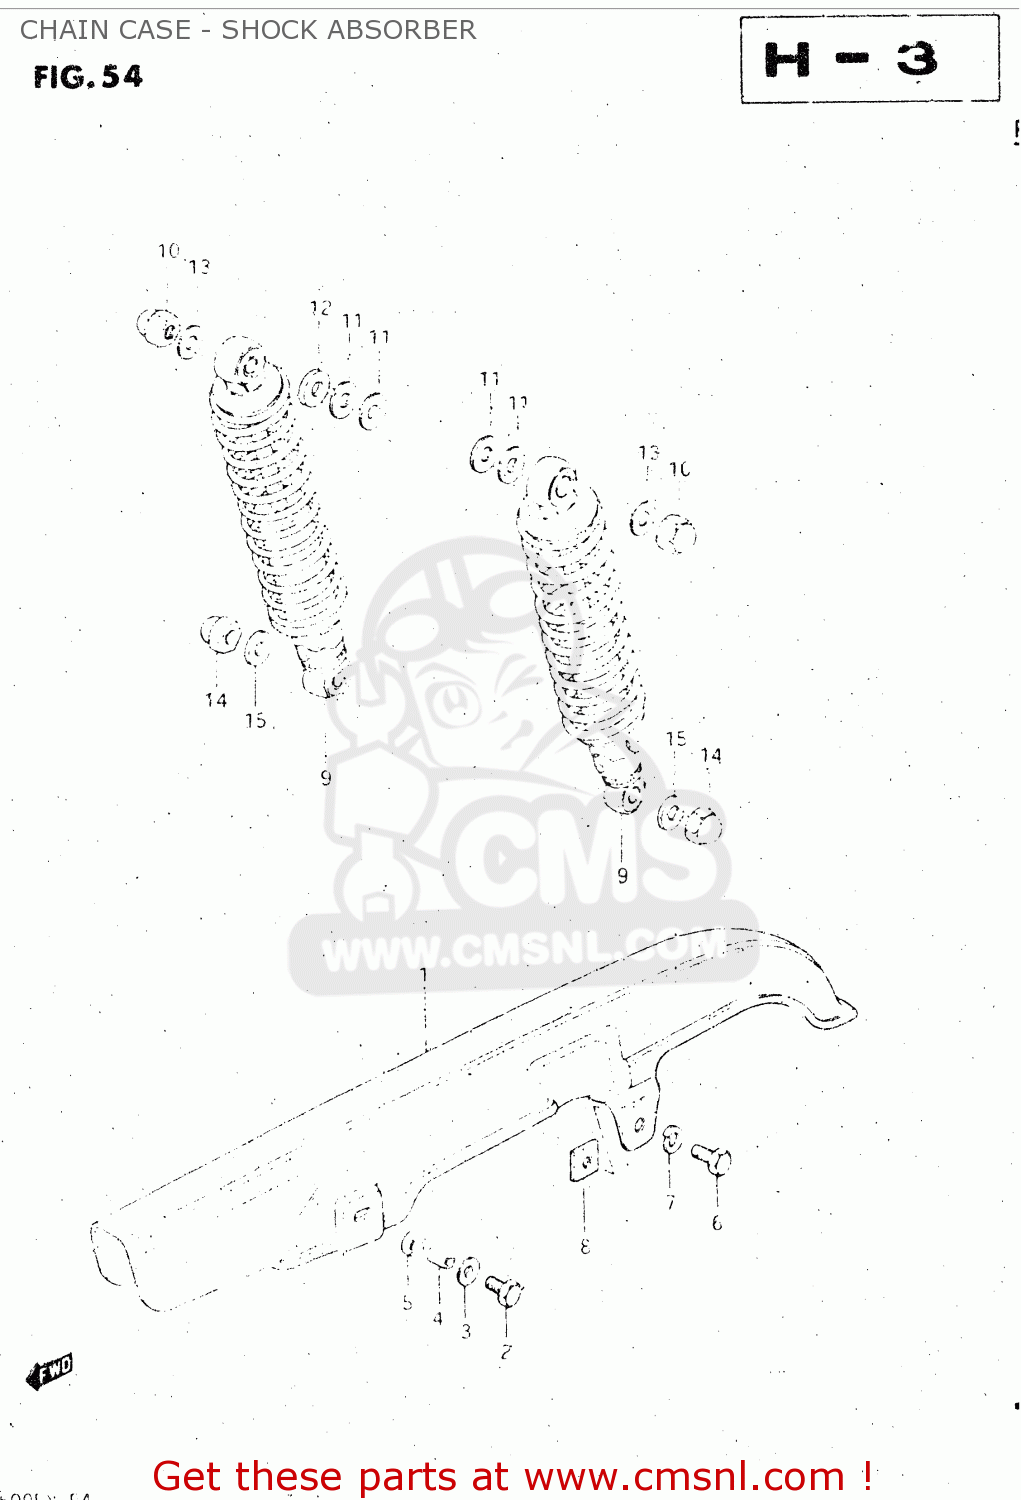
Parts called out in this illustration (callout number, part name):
1	CASE,CHAIN
2	BOLT
3	WASHER(6.5X18X1)
4	SPACER (6.1X8X5.2)
5	CUSHION
6	BOLT, UPPER
7	LOCK WASHER
8	NUT,CHAIN CASE RR
9	SHOCK ABSORBER, REAR
10	NUT
11	WASHER
12	WASHER (12.5X24X3.2)
13	WASHER
14	NUT, LOWER LH
15	WASHER
